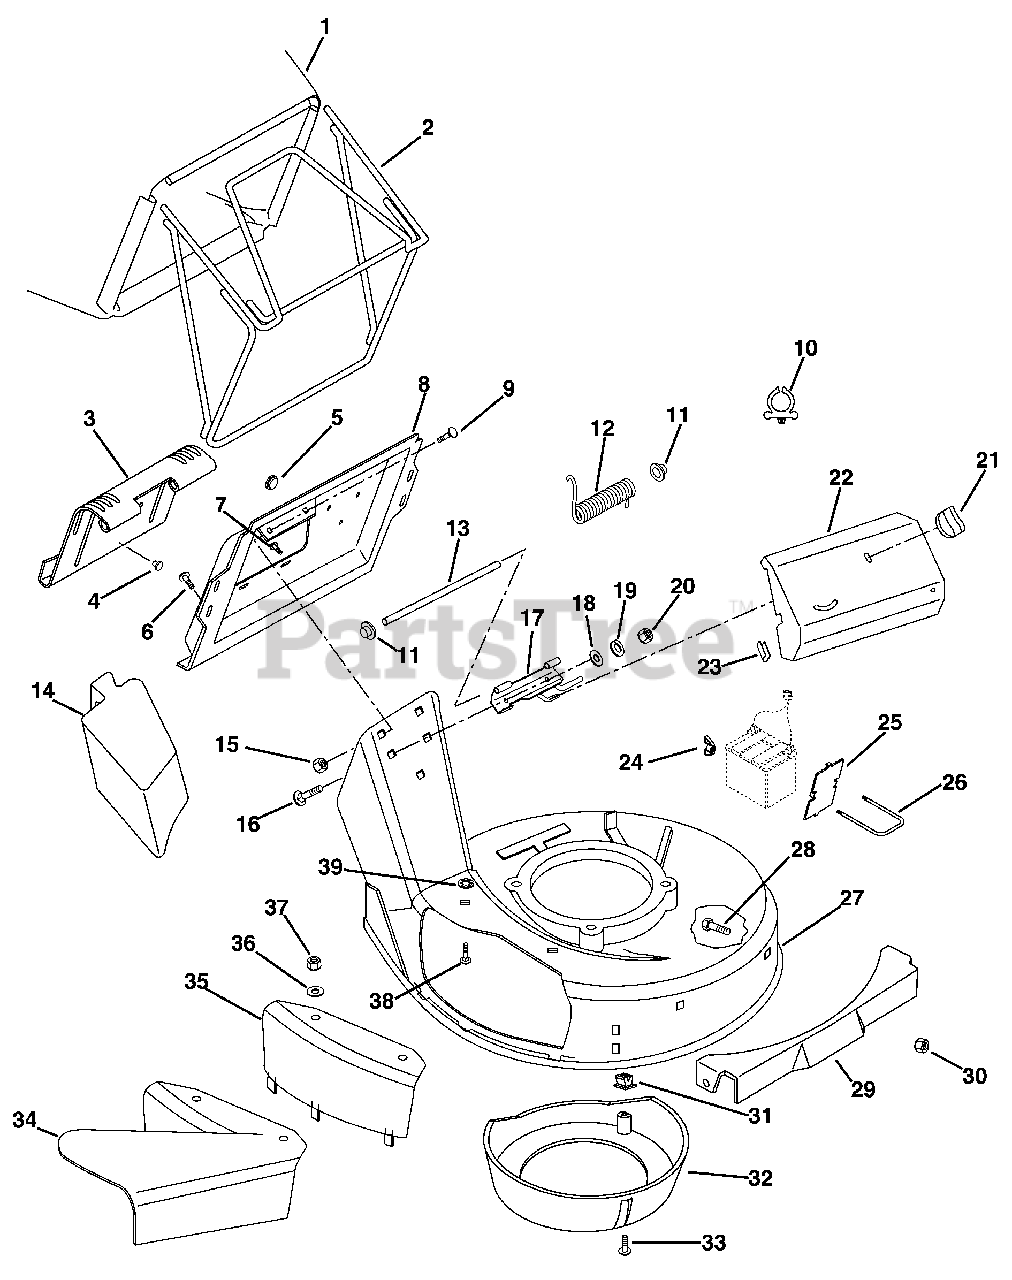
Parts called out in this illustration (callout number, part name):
1	Bag-Consumer Black
2	Bagger Frame
3	Door-Catcher Plate
4	Button Bumper
6	Screw-Tapping 12-24 x .50 Hex Washer Head (580 RSW, 600 C)
7	Screw-Tapping 10-24 x .375 Hex Washer Head (580 RSW, 600 C)
8	Plate-Catcher
9	Bolt-Round Head Square Neck .25-20 x .38
10	Snap-in Clip (580 RSE)
12	Spring-Torsion .120 x .68 x 3.09
14	Mulch Master Mulcher Accessory
15	Nut-Locking-Flange .25-20
16	Bolt-Round Head Square Neck .25-20 x .75 Grade 5
17	Hinge Base Weldment
18	Washer-Flat-Steel .328 x .87 x .179
19	Washer-Locking .25 x .077
20	Nut-Hex .25-20
22	Drive Cover
23	Trim Bumper
24	Nut-Wing #8-32
25	Battery Plate (580 RSE)
26	U-Bolt (580 RSE)
27	Mower Pan Head w/ Decals
28	Bolt-Round Head Square Neck .31-18 x .50 Grade 5 (580 RS, 580 RSE, 580 RSW)
29	Front Panel (580 RS, 580 RSE, 580 RSW)
30	Nut-Locking-Center .31-18 (580 RS, 580 RSE, 580 RSW)
31	Grommet-Plastic
32	Baffle-Center
33	Screw-Tapping 10-16 x .62 Hex Washer Head
34	Side Discharge Assembly
35	Side Discharge Cover
36	Washer-Flat-Steel .406 x .812 x .065
37	Nut-Locking-Nylon .312-18
38	Bolt-Round Head Square Neck .31-18 x .75 Grade 2
39	Nut-Push .312
